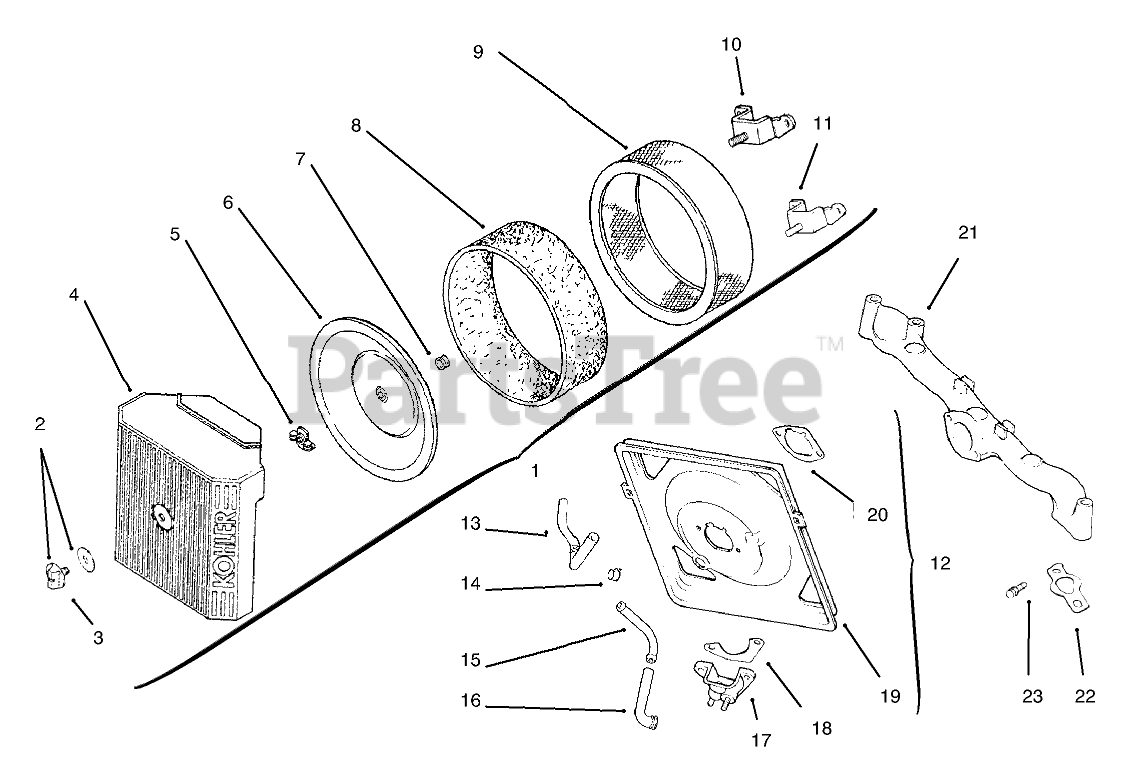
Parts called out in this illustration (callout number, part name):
1	Kit-Air Cleaner Cover
2	Kit-Knob w/Gasket
3	Knob-Cover
4	Cover-Air Cleaner
5	Wingnut
6	Cover-Inner AirCleaner
7	Seal, insert
8	Bement-Precleaner
9	Bement-Air Cleaner
10	Bracket-Air Cleaner
11	Bracket-Air Cleaner
12	Kit-Air Cleaner Base
13	Hose-Breather
14	Clamp
15	Fitting
16	Hose-Breather
17	Cup-Fuel Spitback
18	Gasket-Fuel Spitback
19	Base-Air Cleaner
20	Gasket-A/C Base
21	Manifold-Intake
22	Gasket-Intake, Manifold
23	Screw
